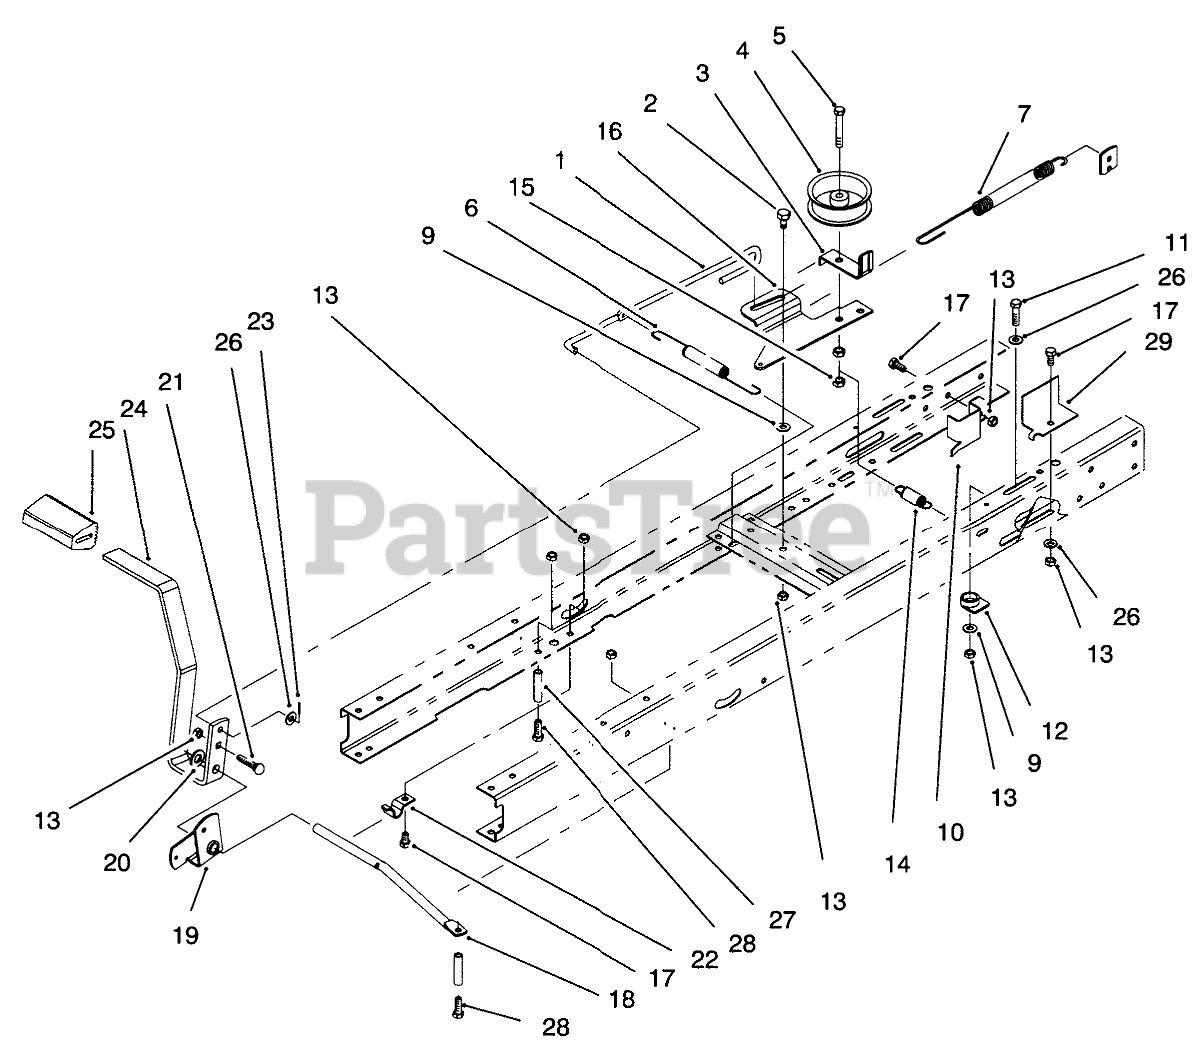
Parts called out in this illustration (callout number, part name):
1	ROD-CLUTCH/BRAKE
2	BOLT-SHOULDER
3	GUIDE-IDLER, BELT
4	Idler Pulley
5	SCREW-HH
6	SPRING-EXTENSION
7	SPRING-BRAKE
8	SCREW-HH
9	WASHER-PIVOT
10	BRACKET-BELT, GUIDE
11	SCREW-HH
12	GUIDE-CABLE
13	NUT-LOCK, NI
14	SPRING-EXTENSION
15	NUT-LOCK, NI
16	ARM-IDLER
17	SCREW-HH
18	ROD-PIVOT, PEDAL
19	BelIcrank
20	WASHER-FLAT
21	SCREW-CARR
22	CLAMP-PIVOT, SHIFT
23	PIN-COTTER
24	Pedal-Clutch/Brake
25	PAD-PEDAL
26	WASHER-PLAIN
27	TUBING-SPACER
28	SCREW-HH
29	BRACKET-BELT, GUIDE
